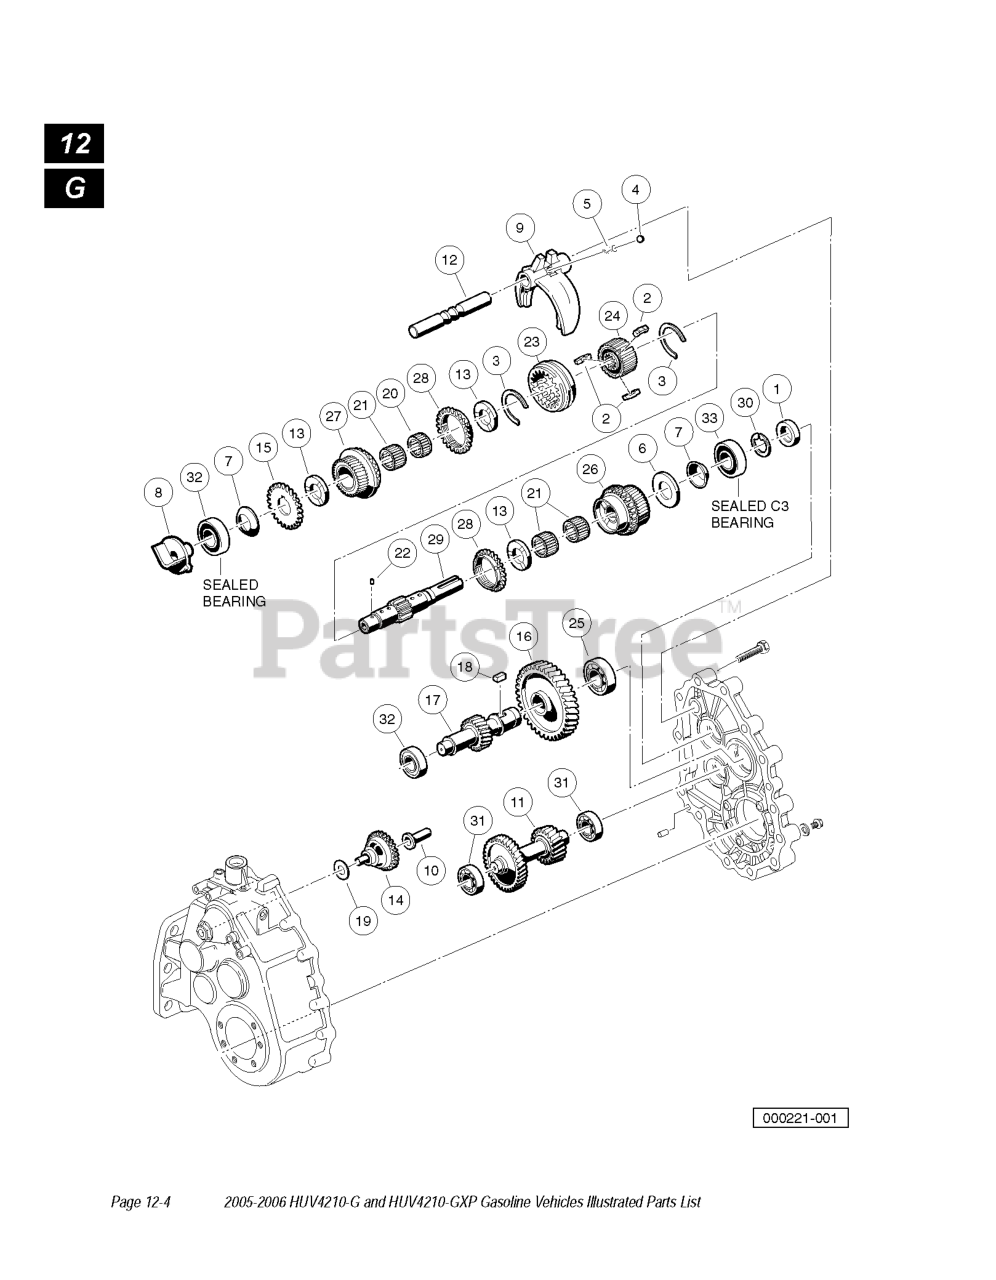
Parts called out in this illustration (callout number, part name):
2	SYNCHRO INSERT
3	SYNCHRO SPRING
4	Shifter Ball
5	SHIFTER SPRING
6	THRUST WASHER
7	SPRING WASHER
9	FORK-SHIFT
10	SLEEVE - GOVERNOR
11	GEAR - CLUSTER
13	PLATE-THRUST
14	GOVERNOR ASSEMBLY
16	GEAR HELICAL
17	GEAR HELICAL
20	BEARING, NEEDLE
21	NEEDLE BEARING
22	PIN, .116" DIA X .264 DOWEL
23	SLEEVE, SYNCHRO
24	HUB, SYNCHRO CLUTCH
25	BEARING, BALL
26	GEAR ASSY, 16 DEG FRT SYNCHRO
27	GEAR ASSY, 16 DEG REAR SYNCHRO
28	RING, 16 DEGREE SYNCHRONIZER
29	SHAFT, TRANS, W/ CIRCLIP
30	CIRCLIP, TRANS INPUT SHAFT
32	SEALED BALL BEARING (7336)
33	SEALED BALL BEARING(101927801)
